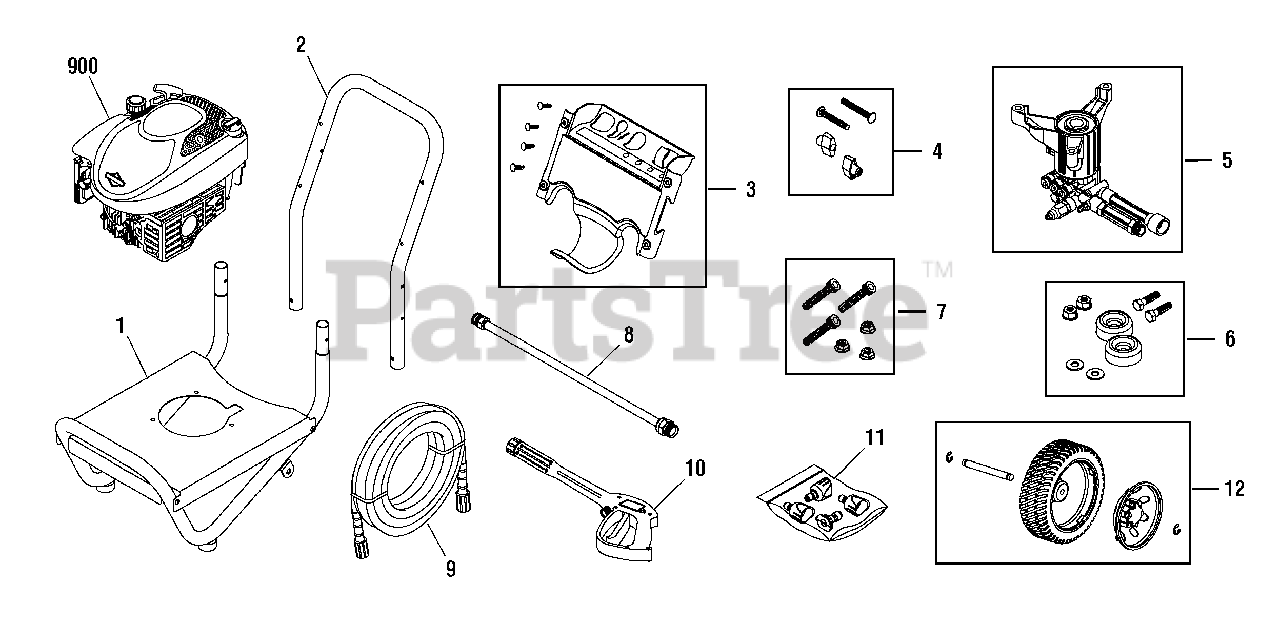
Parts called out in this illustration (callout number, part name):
4	KIT, Hardware, Handle
5	PUMP
6	MOUNT, Vibration
7	KIT, Hardware, Pump
8	EXTENSION, QC
10	GUN
11	KIT, Nozzle
900	** ENGINE
